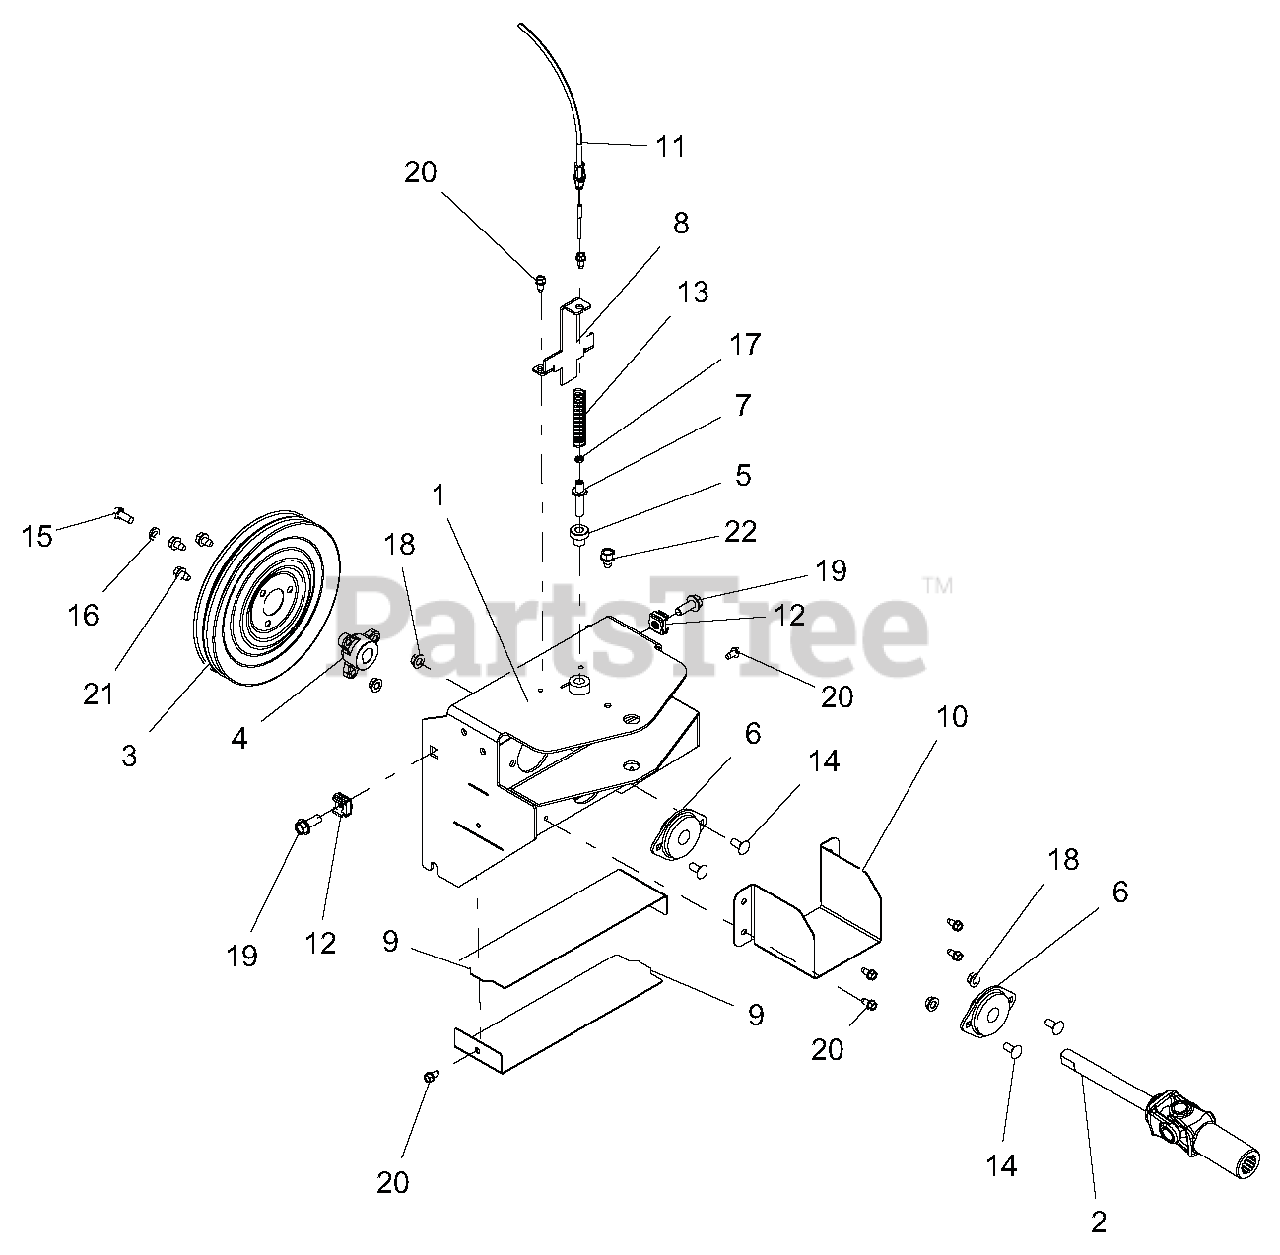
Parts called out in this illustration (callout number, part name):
1	ADAPTOR, 36" BRUSH, 926 FRAME
2	DRIVELINE, SERIES 07 (U-JOINT)
3	PULLEY, SPIN FORM DUAL GROOVE
4	PULLEY HUB, BOLT-ON D-BORE .75
5	SPACER -FLANGED .390X.500X.781
6	BEARING, 2 BOLT FLANGE -.75 ID
7	PIN, ADJUSTABLE ANGLE BRUSH
8	BRKT, PIN HOLDER
9	GUARD, BRUSH PTO
10	GUARD, BRUSH U-JOINT
11	CABLE, REMOTE BRUSH LOCK
12	NUT-RETNR .38-16 TINRMAN
13	SPRING, COMPRESSION
14	@BLT-RDHDSQNK .31-18X.75 G5YZ
15	BLT-HEX .31-24X.75 YWZC GR5
16	WSHR-LK .312X.097 HVY YWZC
17	@NUT-HEX 10-24 YWZC
18	@NUT-LK-TOP-FLG .31-18 YWZC
19	BLT-SERHFWH .375-16X1.0 YWZC
20	SCR-TAP .25-20X.50 HWH TR YWZ
21	@SCR-TAP .31-18X.50 HWH TR YWZ
22	@SCR-TAP .38-16X.50 HWH TR YWZ
